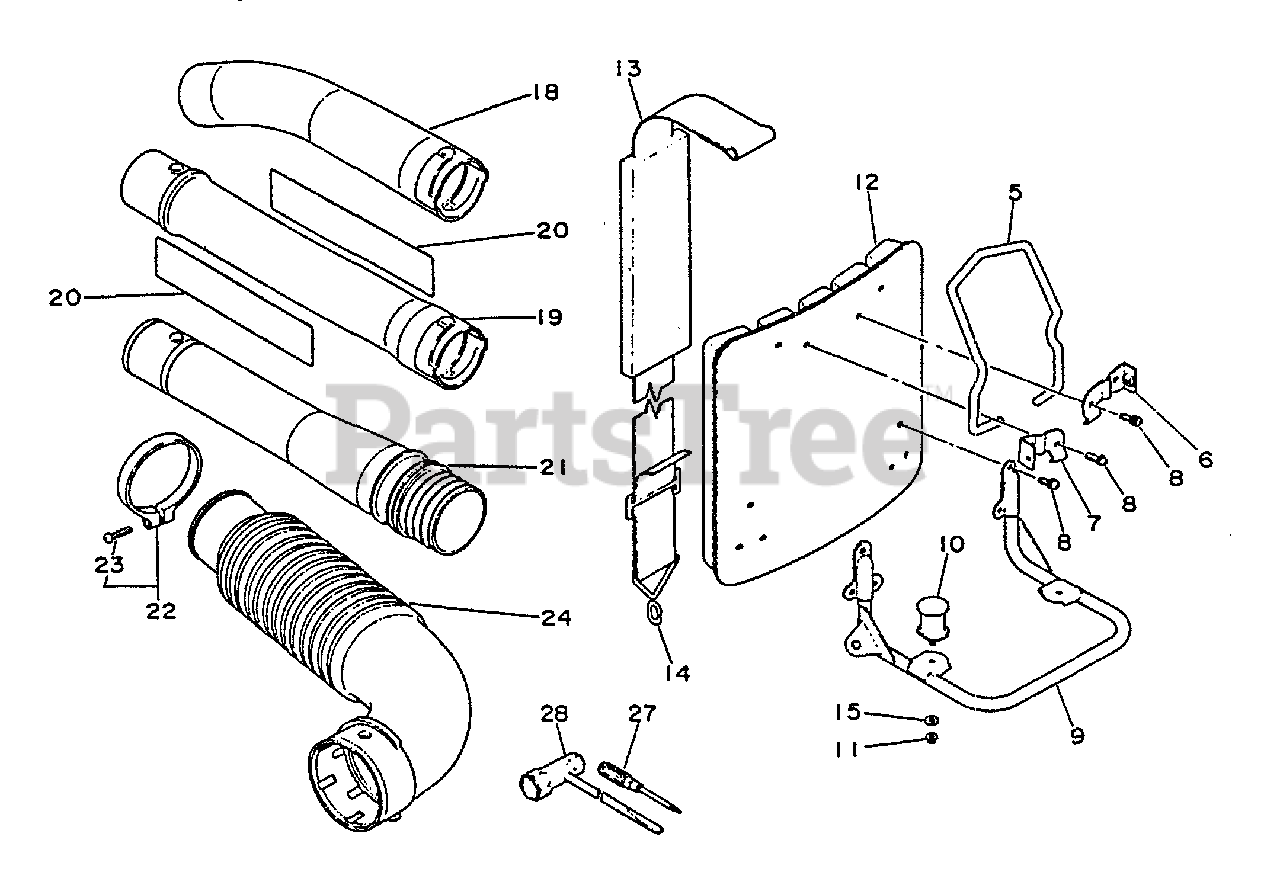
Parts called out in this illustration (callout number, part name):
7	BRACKET, HANGER
8	SCREW - 5X10
9	STAND
11	NUT - 6 -- FLANGE
12	CUSHION, BACKPACK
13	BACKPACK STRAP ASSY
14	RING, STRAP
15	WASHER - 6.5
18	TUBE, BLOWER - CURVED
19	TUBE, BLOWER - STRAIGHT
20	LABEL - ECHO
21	TUBE, BLOWER - SWIVEL
22	CLAMP KIT
23	SCREW - 5X20
24	TUBE, BLOWER - FLEXIBLE
27	SCREWDRIVER - (+)
28	T-WRENCH - 10X19mm
